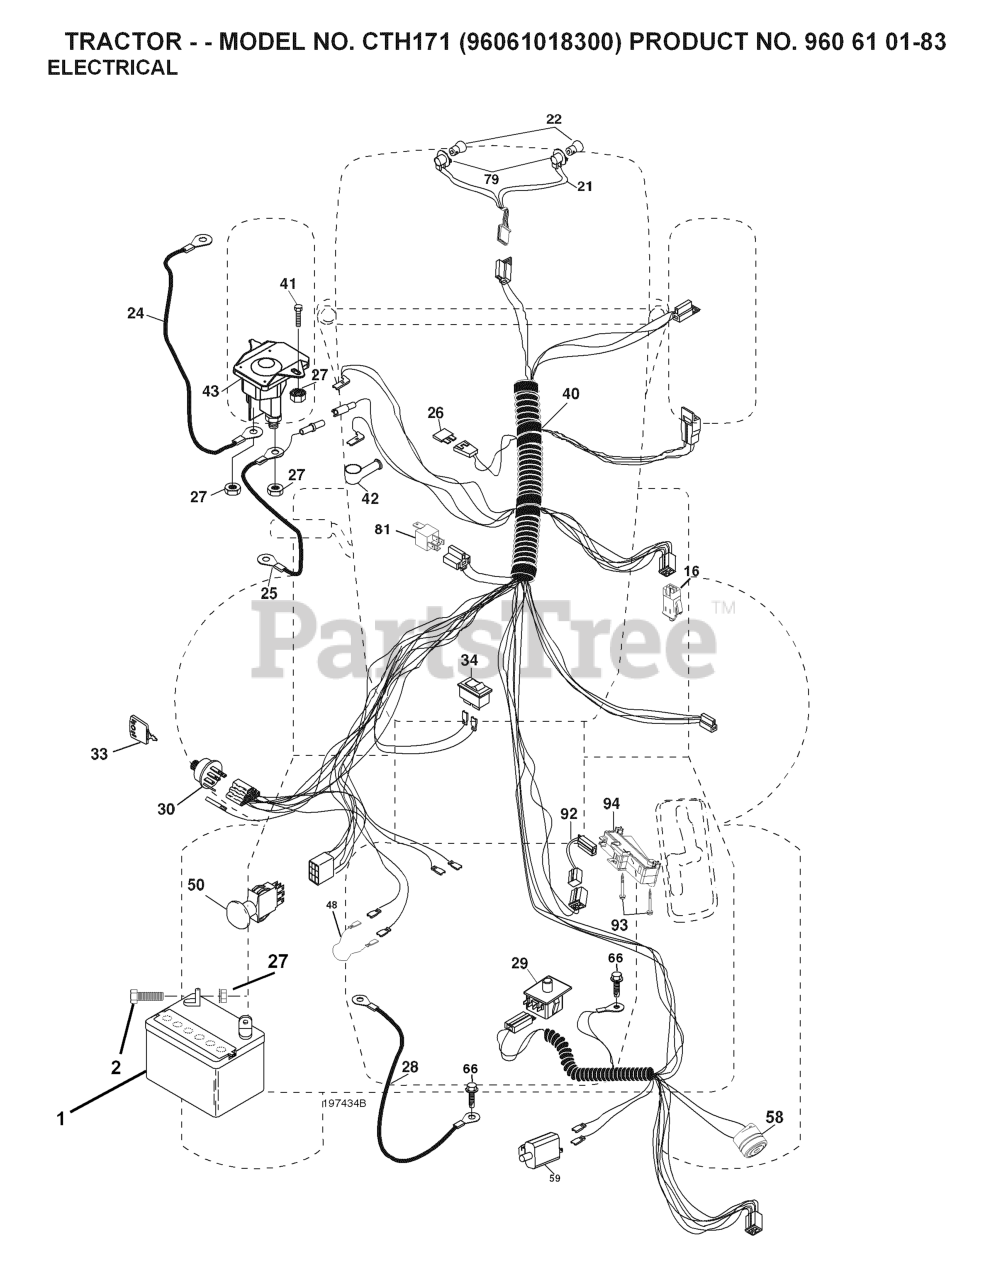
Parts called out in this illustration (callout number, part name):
1	BATTERY 12V .35 AMP
2	BOLT.HEX.1/4.X.3/4.DICHROMATE
16	SWITCH INTERLOOK PUSH-IN
21	HARNESS.LIGHT W/4152J BULBS
24	BATTERY CABLE GT
25	CABLE BATTERY
26	FUSE 20AMP
27	NUT
28	CABLE GROUND
29	SWITCH.SEAT.DP W/RAMPS
30	SWITCH.IGN.DELTA.W.LGH.ROS
33	KEY MLD GEN DELTA
40	RP HARNESS.IGN.ELECT.REG.CRD
41	BOLT
42	TERMINAL COVER
43	SOLENOID.W/BRASS.PLUNGER
48	ADAPTER.AMMETER
50	RP.PTO.SWITCH.8 TERMINAL.BLACK
58	BUZZER
59	.WITCH.FULL BAGGER.INDICATOR
79	BULB HOLDER ASM.
81	RELAY.ASSY.T
92	HARNESS.PIGTAIL.CONSLE
93	SCREW.PLASTITE
94	MODULE.REVERSE.ROS
